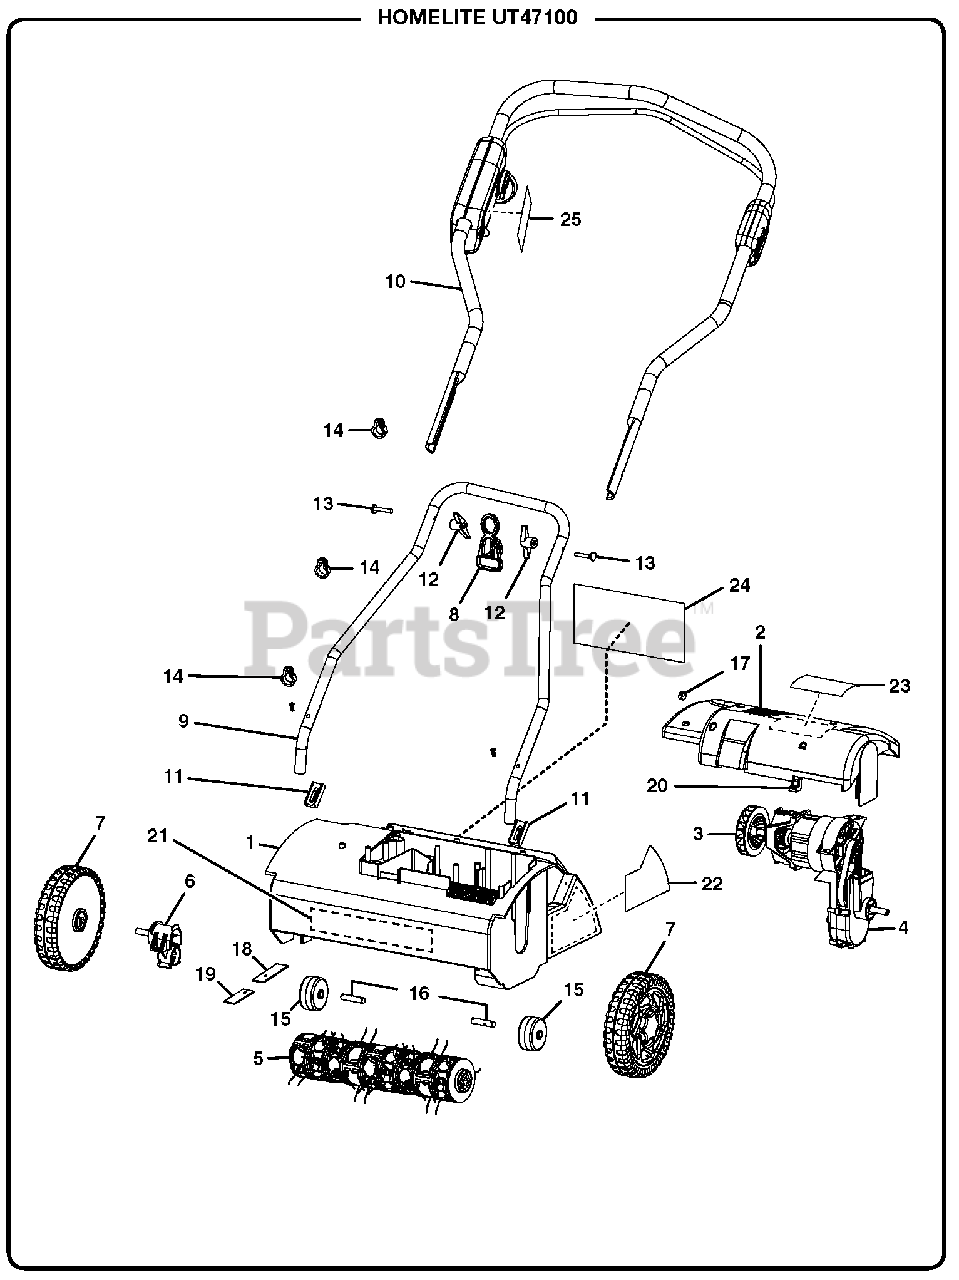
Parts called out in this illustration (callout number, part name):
2	Motor Cover
3	Motor Assembly
4	Gear Case Assembly
5	Tines Assembly
7	Wheel Assembly
8	Cord Retainer
9	Lower Handle
10	Upper Handle Assembly
11	Rubber Cushion
13	Bolt (need size)
15	Rear Wheel Assembly
16	Shaft (Rear Wheel)
17	Strain Relief
18	Cover (Large)
19	Cover (Small)
20	Motor Support
21	Front Logo Label
22	Height Adjustment Label
23	Performance Label
24	Warning Icon/Data Label
25	Start Label
